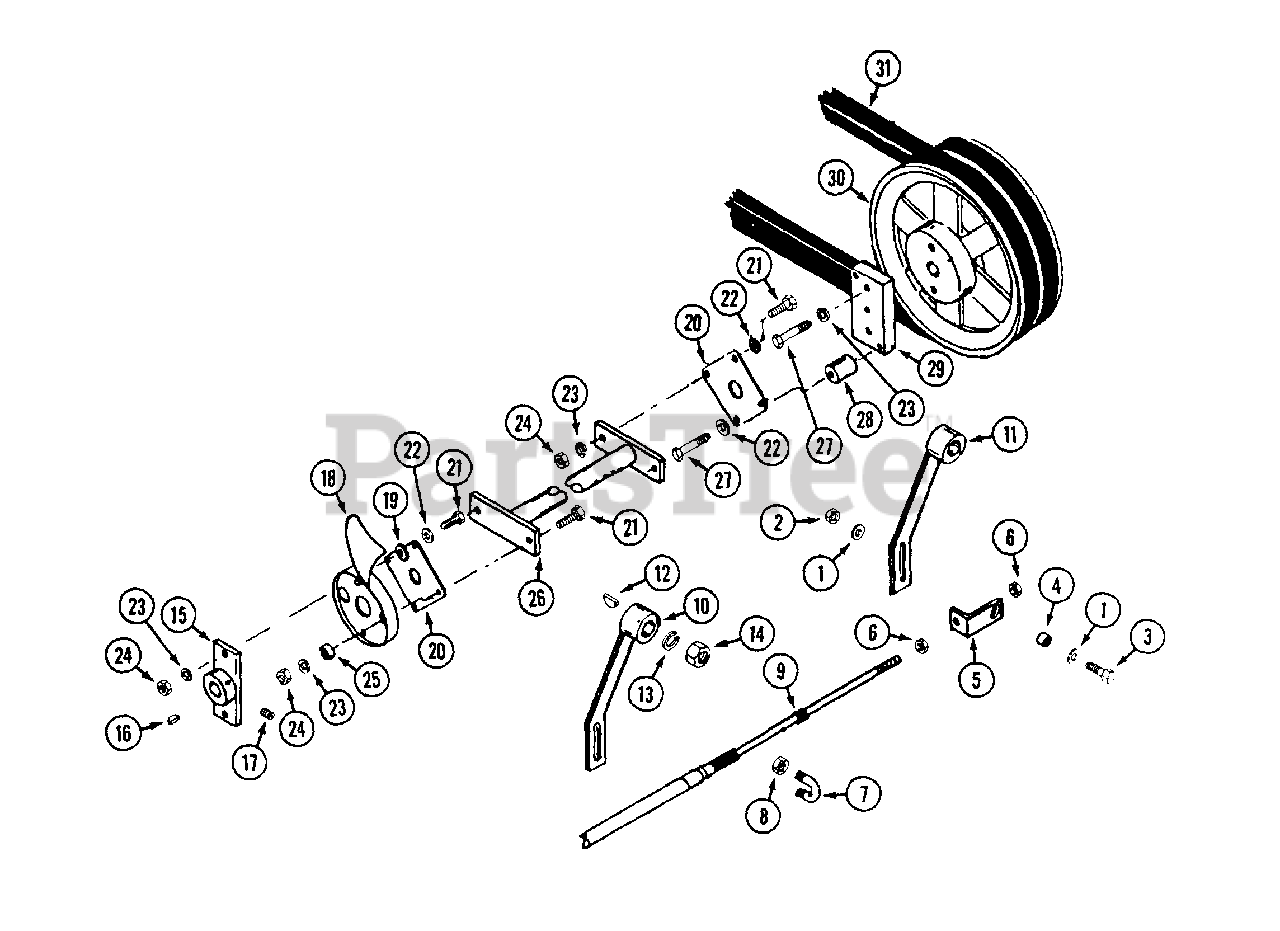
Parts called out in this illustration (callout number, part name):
1	WASHER - 1/4"
2	NUT - 1/4" - 20 lock
3	BOLT - 1/4" - 20 x 1"
4	BUSHING - steering cable
5	BRACKET - steering cable end
6	NUT - 1/4" - 20 lock
7	CLAMP - cable
8	NUT - 5/16" - 18 lock
9	CABLE - steering
10	ARM - control L.H.
11	ARM - control R.H.
12	KEY - 1/8" x 5/8" woodruff
13	LOCKWASHER - 1/2"
14	NUT - 1/2" - 13
16	KEY - 3/16" x 3/4" woodruff
17	SETSCREW - 5/16" - 18 x 5/16"
19	WASHER - .33" x .69" x .13"
20	PLATE - drive
21	BOLT - 5/16" - 18 x 1"
22	WASHER - .312" x .75"
23	LOCKWASHER - 5/16"
24	NUT - 5/16" - 18
25	SPACER - 1/4"
26	SHAFT - cross
27	BOLT - 5/16" - 18 x 1-1/4"
28	SPACER - 3/4"
29	BLOCK - cross shaft
30	PULLEY - pump drive
31	BELT - engine to transmission
